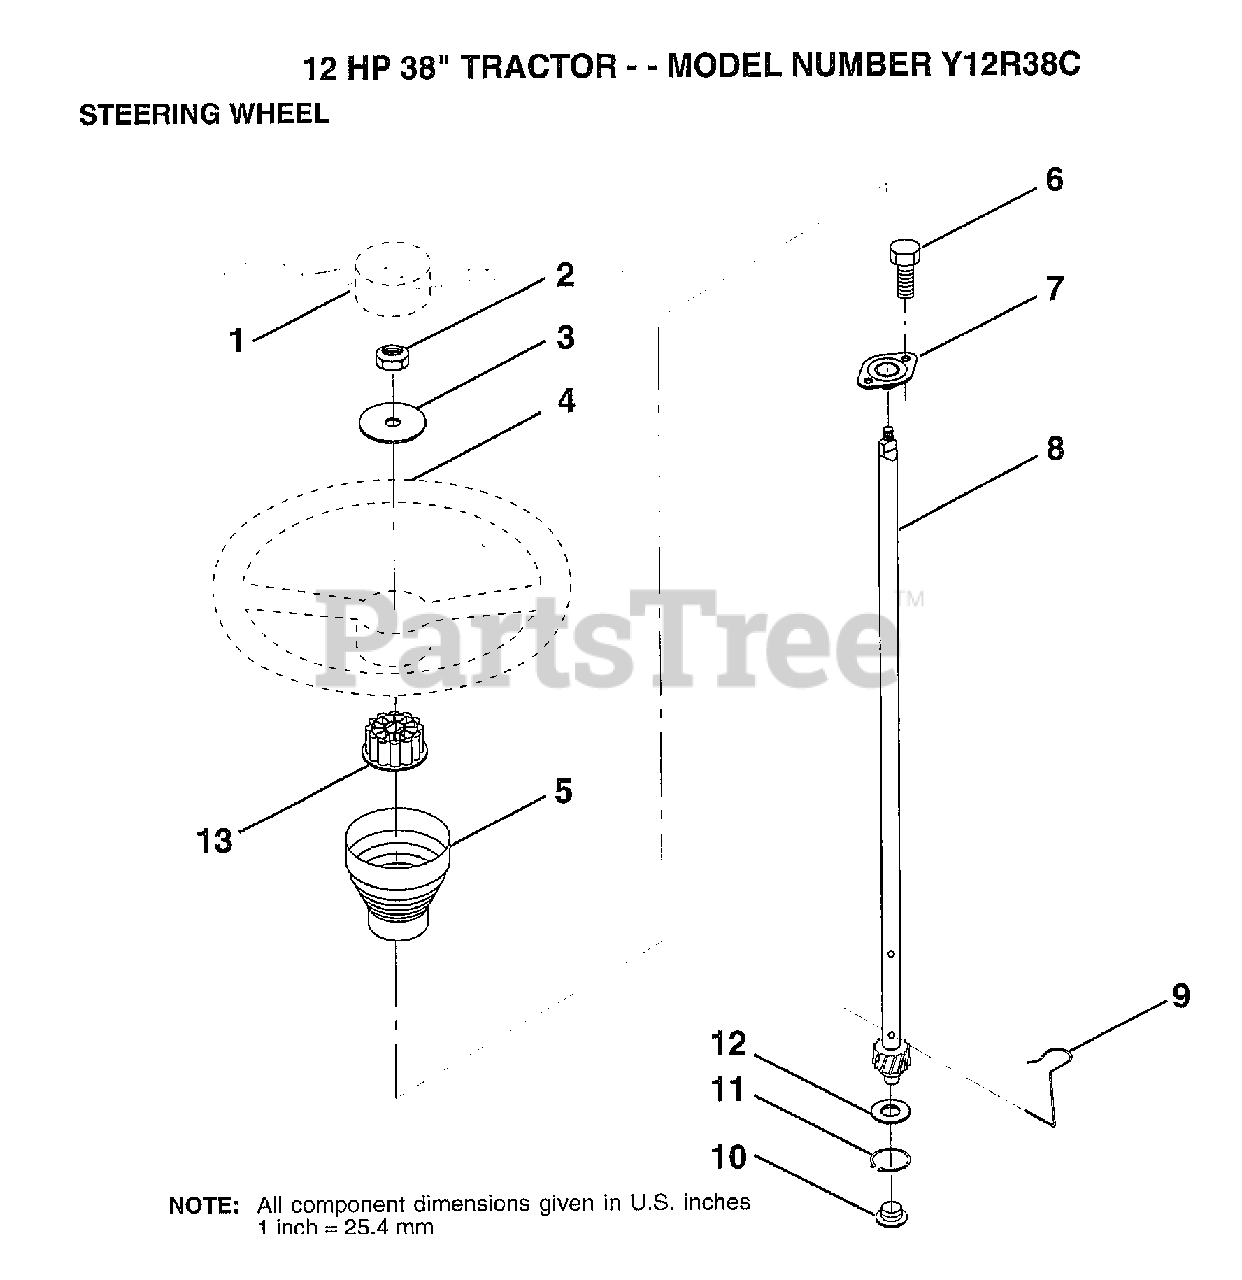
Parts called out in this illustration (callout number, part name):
1	INSERT STEERING
2	GRIPCO NUT
3	WASHER T
5	SLEEVE STEERING
9	STEERING CLIP
10	BUSHING STEER LWR
11	RING
12	WASHER LT
13	ADAPTER-WHEEL LT
